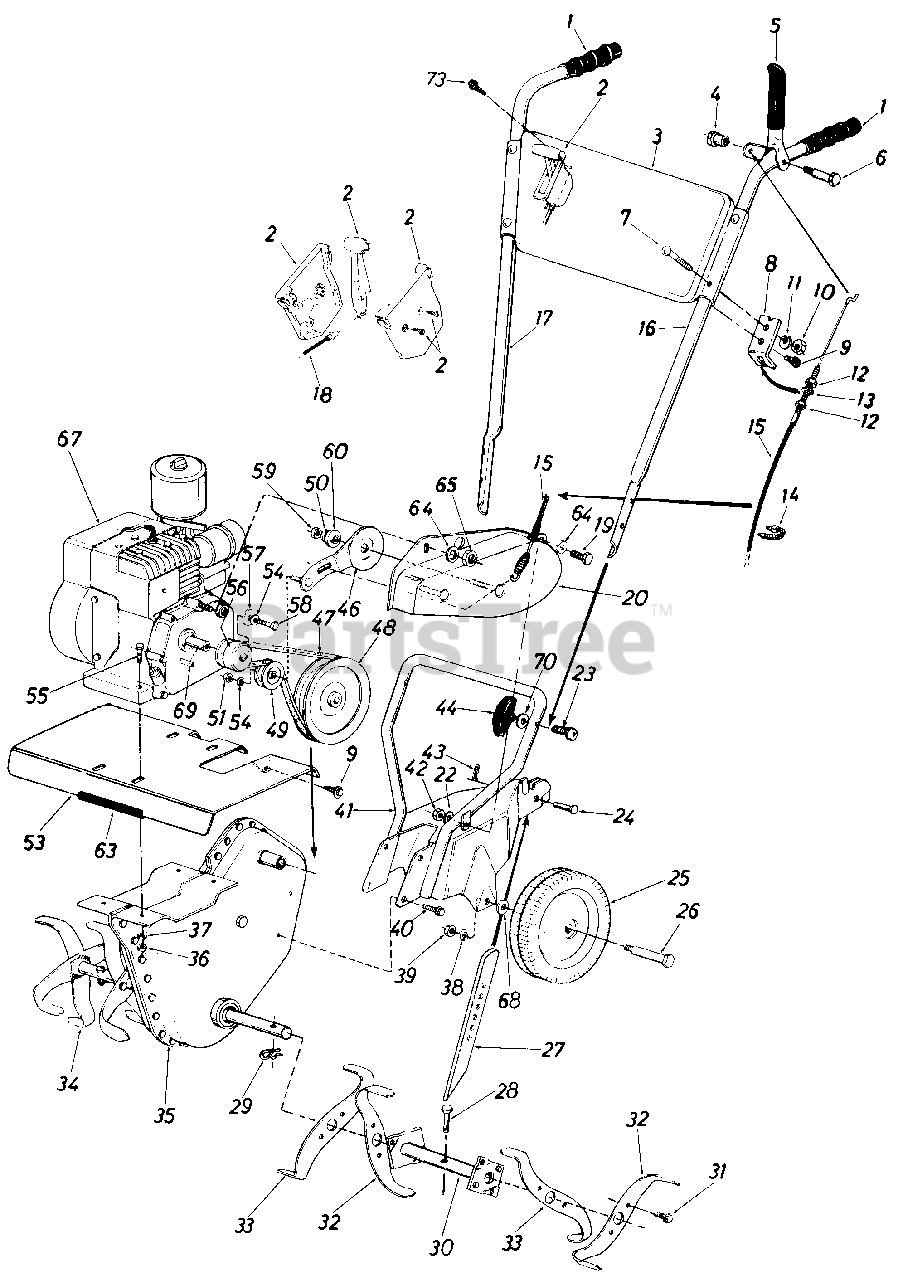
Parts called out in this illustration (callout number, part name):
2	Throttle Control Box Ass'y.
3	Handle Panel
4	Shoulder Nut
5	Clutch Grip Ass'y.
6	Shoulder Bolt 3/8 x 1.160" Lg.
7	Carriage Bolt 5/16-18 x 1.5" Lg.
8	Cable Support Bracket
9	Hex Wash. Hd. Self-Tap Scr. 1/4-20 x .50" Lg.
10	Hex Nut 5/16-18 Thd.
11	L-Wash. 5/16" I.D.
12	Hex Jam Nut 5/16-24 Thd.
13	L-Wash. 5/16"-I.D.
14	Cable Tie
15	Clutch Control Cable
19	Hex Bolt 1/4-20 x .75" Lg.
20	Belt Cover Ass'y.
22	L-Wash. 1/4" I.D.*
23	Curved Hd. Bolt 5/16-18 x 1.75" Lg.
24	Clevis Pin
25	Wheel Ass'y. Comp.-Plastic
25	Wheel Ass'y. Comp.-Steel
25	Wheel Bearings
26	Shoulder Bolt
29	Hairpin Cotter
30	Tine Adapter Ass'y.
31	Hex Wash. Hd. Self-Tap Scr. 1/4-20 x .50" Lg.
32	Tine Blade-L.H.
33	Tine Blade-R.H.
34	Tine Ass'y. Comp.
35	Chain Case Ass'y. Comp.
36	Hex Nut 5/16-18 Thd.
37	L-Wash. 5/16" I.D.*
38	L-Wash. 3/8" I.D. (Heavy Duty)
39	Hex Cent. L-Nut 3/8-16 Thd.
40	Hex Wash. Hd. Self-Tap Scr. 5/16-18 x .50" Lg.
43	Internal Cotter Pin
44	Hand Knob
46	Idler Arm Ass'y.
47	Belt 3/8" x 29" Lg.
48	Chain Case Pulley 5 1/2 x 1/2"
49	Fl-ldler 2"
50	L-Wash. 5/16" I.D.
51	Hex Nut 3/8-24 Thd.
55	Hex Bolt 5/16-18 x 1.50" Lg.
56	Engine Pulley 3/8 V x .75 I.D. x 2" O.D.
57	Fl-Wash. .385" I.D. x 1.00" O.D.
58	Hex Bolt 3/8-24 x 1.00" Lg.
59	Hex Nut 5/16-18 Thd.*
60	Shld. Spacer .50" Dia. x .133
63	Trim Strip-4"
64	Fl-Wash. .281" I.D. x .500" O.D.
65	Hex Cent. L-Nut 1/4-20 Thd.
67	Engine
68	Bell-Wash.
69	Square Key 3/16 x 3/4" Lg.
70	Bell-Wash.
73	Self-Tap Screw #10 x .5" Lg.
